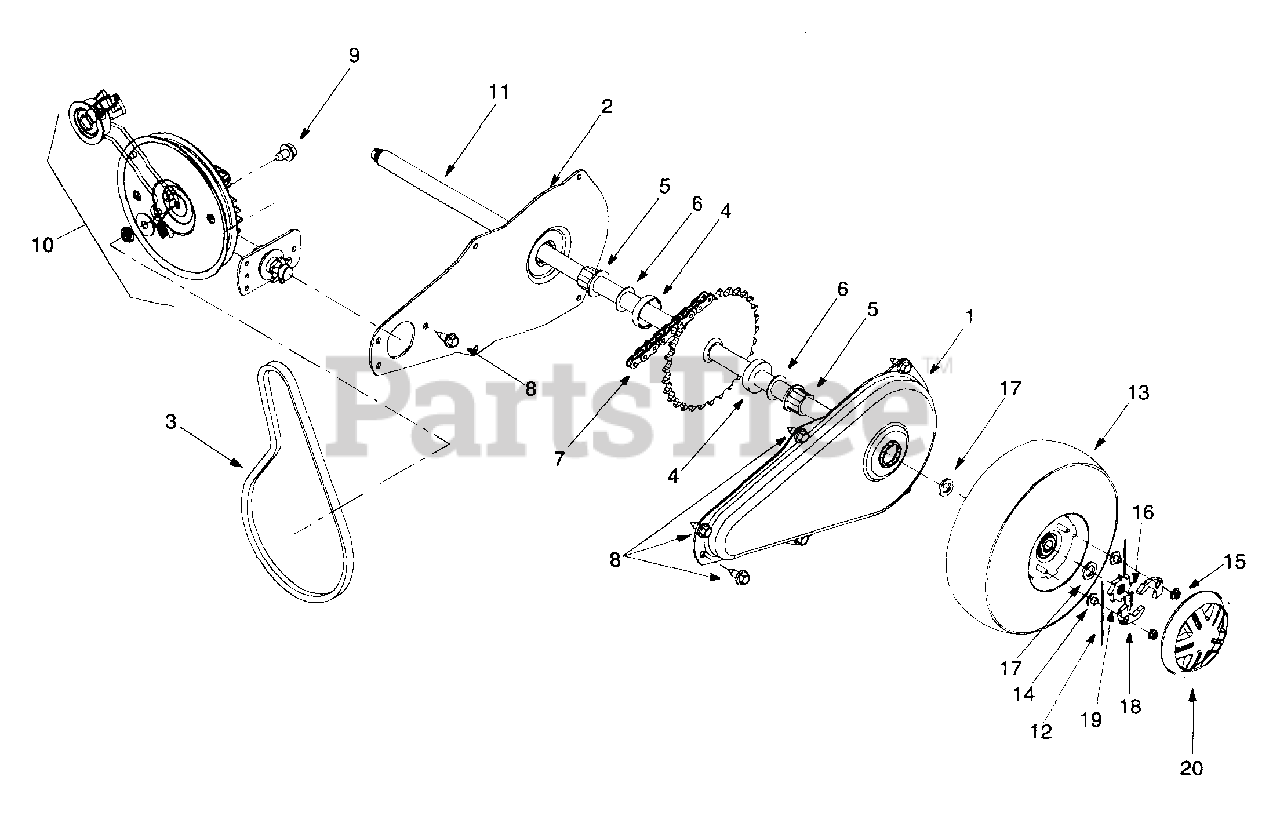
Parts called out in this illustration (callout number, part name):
3	V-Belt, 3/8 x 24.68
4	Spacer, .630 x 1.25 x .29
5	Bearing, Hex Flange, .631 ID
6	Washer, Flat, 5/8 x 1.0
7	Chain, Endless, #41 x 50 Lnks
8	Screw, Hex Wash Hd,
9	Screw, Hex Wash Hd Tapp 5/16-18 x .5
10	Trans. Assembly Complete
11	Shaft Assembly, Axle
12	Spring, Plastic Ratchet
14	Nut, Special Hex 1/4-20
15	Nut, Hex Flange Lock, 1/4-20
16	Pin, internal Cotter
17	Washer, Flat, .64 x 1.12 x .12
18	Pawl, LH .345 ID
19	Ratchet, Wheel, .5 Serr ID x 1.62
20	Hubcap, 4.0
